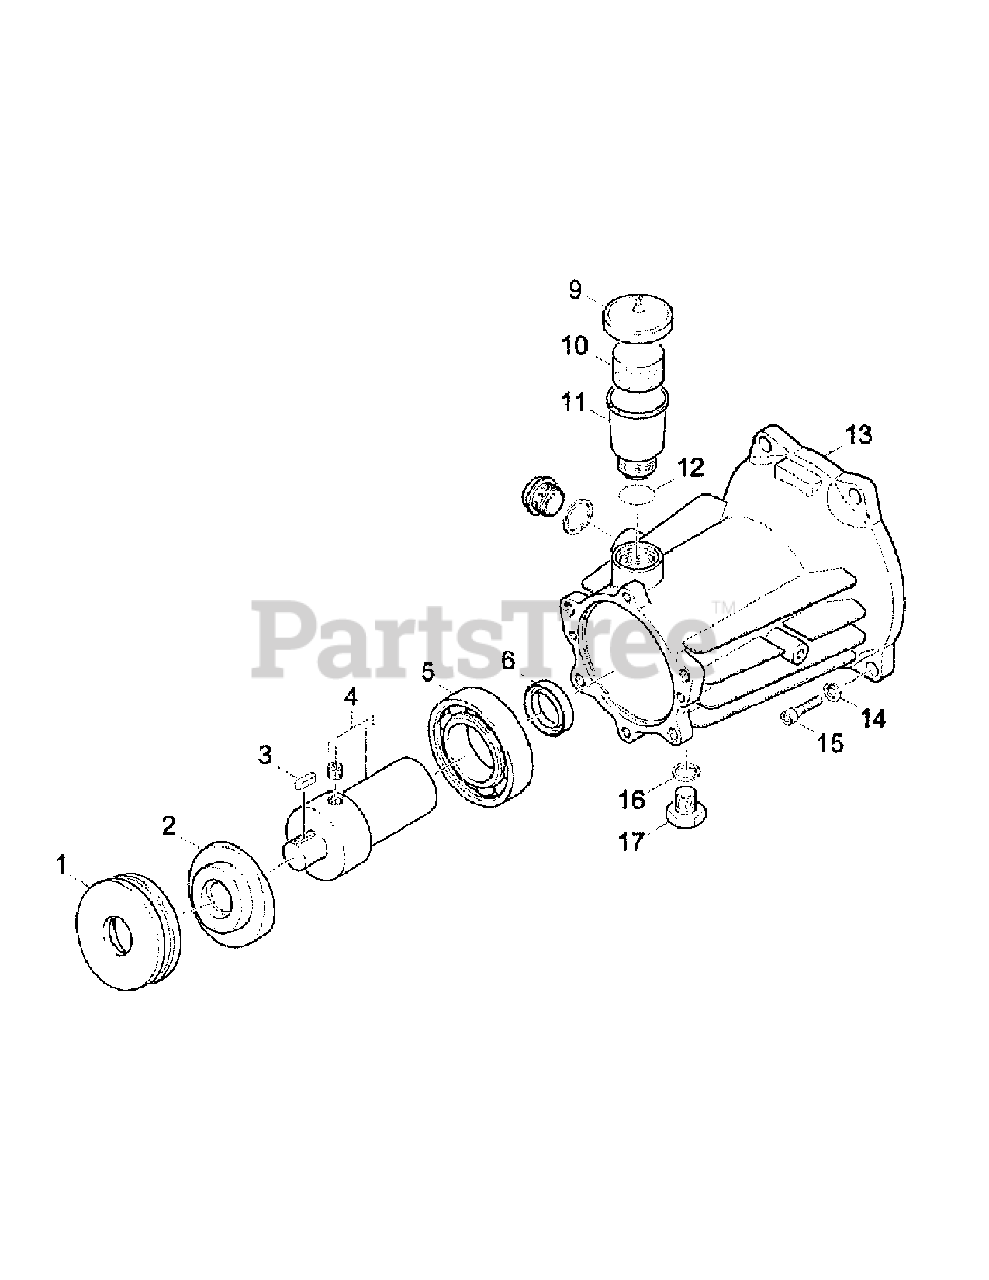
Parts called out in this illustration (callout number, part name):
1	Ball Bearing
2	Swash Plate
3	Spring
4	Coupling Element
5	Cylinder Bearing
6	Shaft Seal
9	Cover
10	Plug
11	Tank
12	Gasket
13	Housing
14	Washer
15	Screw
16	Joint Ring
17	Closing Screw
